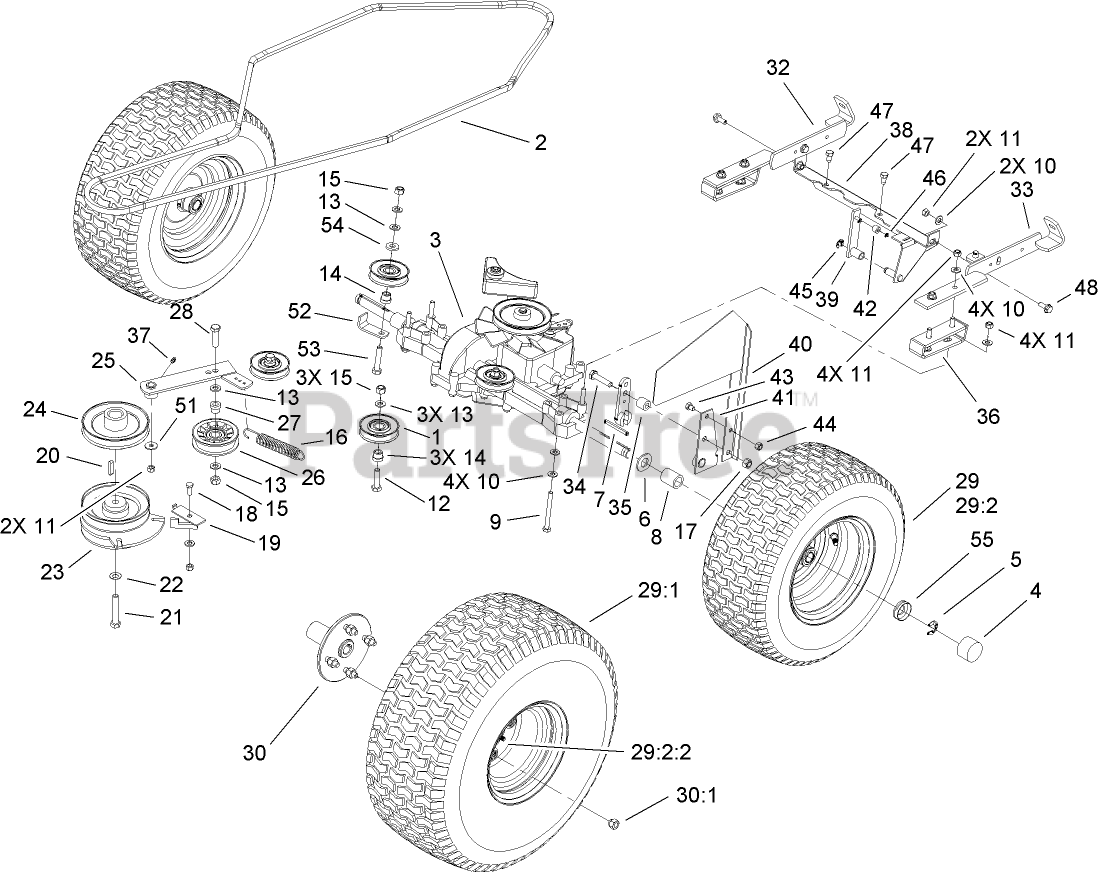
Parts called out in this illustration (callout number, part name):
1	PULLEY-IDLER
2	V-BELT-TRACTION
3	TRANSMISSION
4	CAP-HUB
5	CLIP-SPRING
6	WASHER
7	KEY-SQUARE
8	SPACER-AXLE
9	SCREW-HH
10	WASHER-PLAIN
11	NUT-LOCK, NI
12	SCREW-HH
13	WASHER-FLAT
14	BUSHING-IDLER
15	NUT-LOCK, NI
16	SPRING
17	NUT-LOCK, NI
18	SCREW-HH
19	RETAINER
20	KEY-SQUARE
21	SCREW-HH
22	WASHER-SPRING, BELLEVILLE
23	CLUTCH-ELECTRIC
24	PULLEY-ENGINE
25	ARM-IDLER
26	PULLEY-IDLER
27	BUSHING-IDLER
28	SCREW-HH
29	TIRE AND WHEEL ASM
29:2	WHEEL ASM
29:2:1	Rim
29:2:2	Valve-Tire
30	HUB-WHEEL
30:1	NUT-LUG
32	Bracket-Right
33	Bracket-Left
34	SCREW-HH
35	SLEEVE
36	Plate-Reinforcing
37	FITTING-GREASE
38	Bar ASM
40	ARM-CONTROL, CRUISE
42	Roller
43	SCREW-HH
44	NUT-LOCK, NI
45	Stirrup
46	STIRRUP
47	SCREW-THREAD FORMING
48	SCREW-HEX
51	WASHER-PLAIN
52	RETAINER-BELT
53	SCREW-HH
54	WASHER-FLAT
55	RETAINER-CAP, HUB
